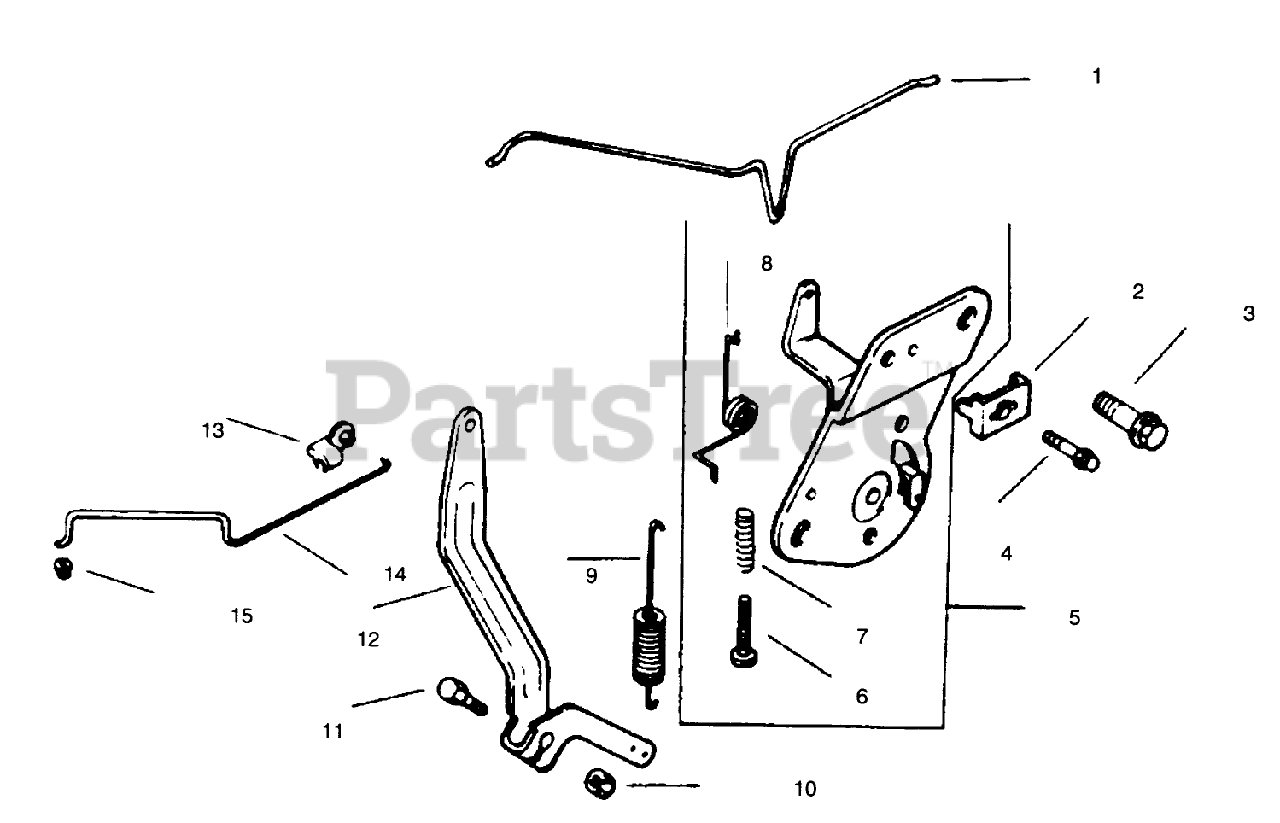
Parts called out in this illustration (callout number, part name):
1	Linkage Choke
2	Clamp
3	Screw
4	Screw
5	Control-Speed ((incl Ref. #6-8)
6	Screw
7	Spring
8	Spring Choke
9	Spring-Governor
10	Nut
11	Screw
12	Lever-Governor
13	Bushing-Linkage
14	Linkage-Throttle
15	Bushing-Linkage
